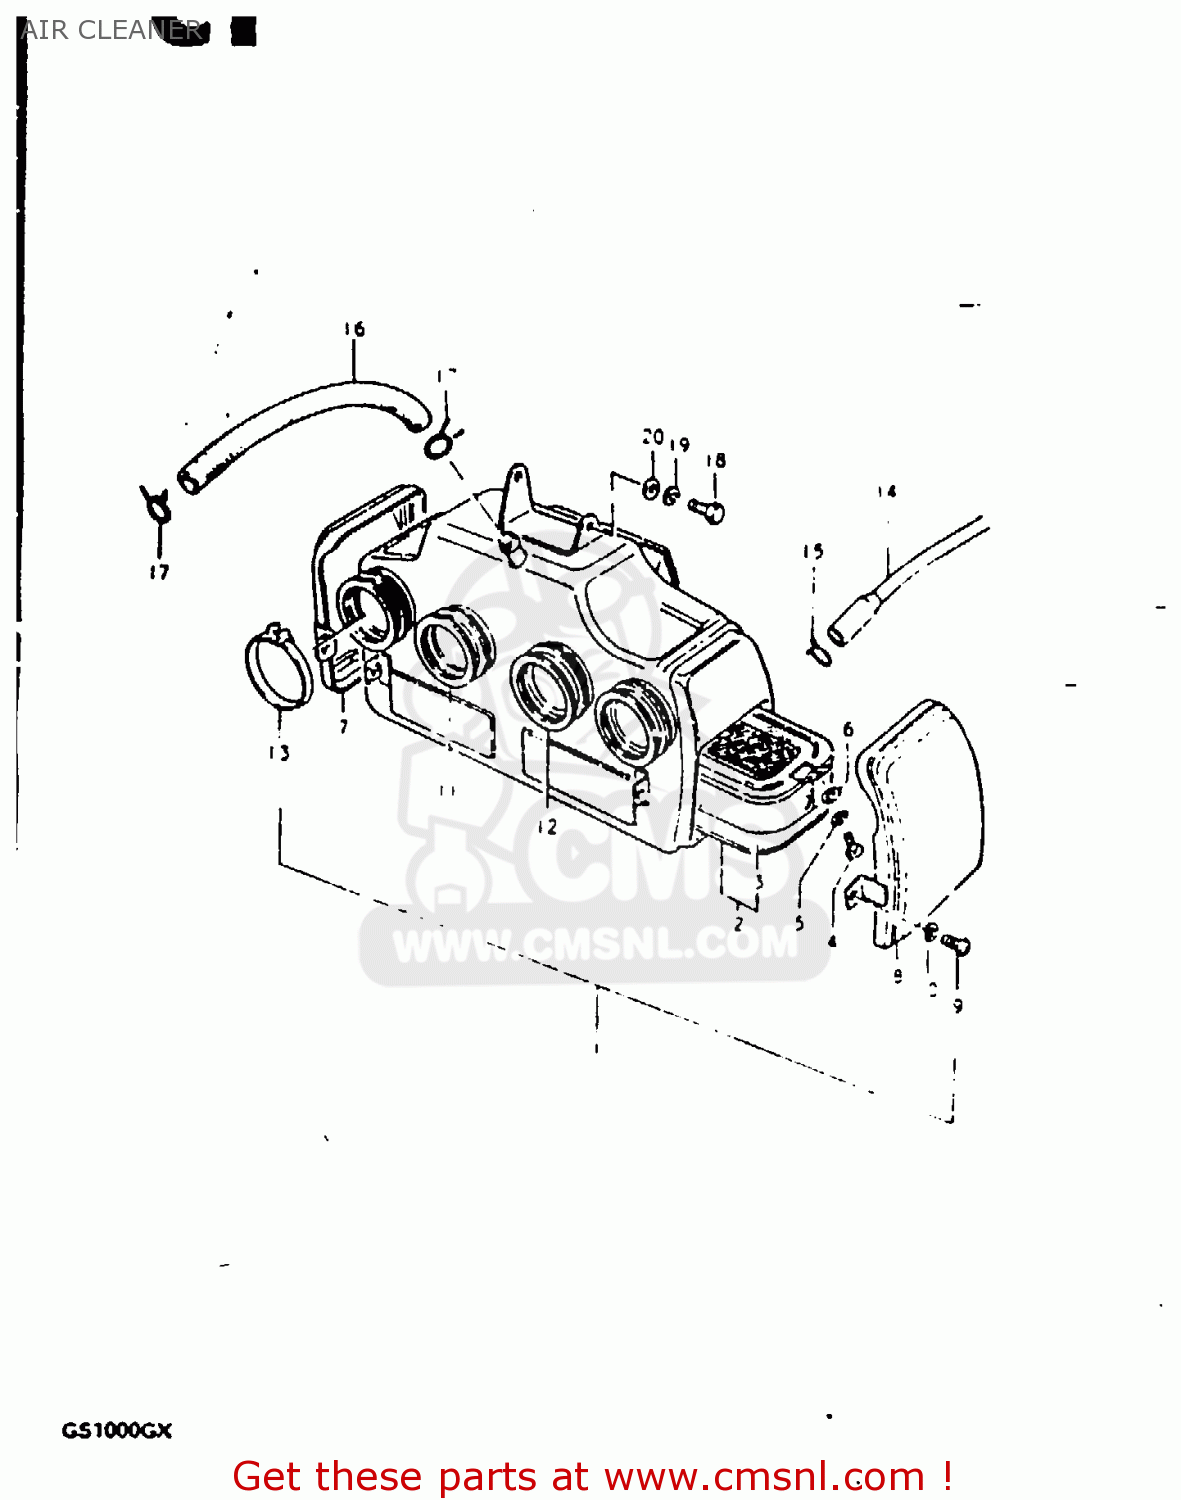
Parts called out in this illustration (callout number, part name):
1	CLEANER ASSEMBLY,AIR
2	FILTER ASSY,AIR CLEANER
3	FILTER
4	SCREW
5	LOCK WASHER
6	WASHER
7	CAP,AIR CLEANER,RIGHT
8	COVER, LH
9	SCREW
10	WASHER
11	HOSE,R
12	HOSE,L
13	CLAMP
14	14-2
15	16
16	HOSE
17	CLIP
18	BOLT
19	LOCK WASHER
20	WASHER 6MM
